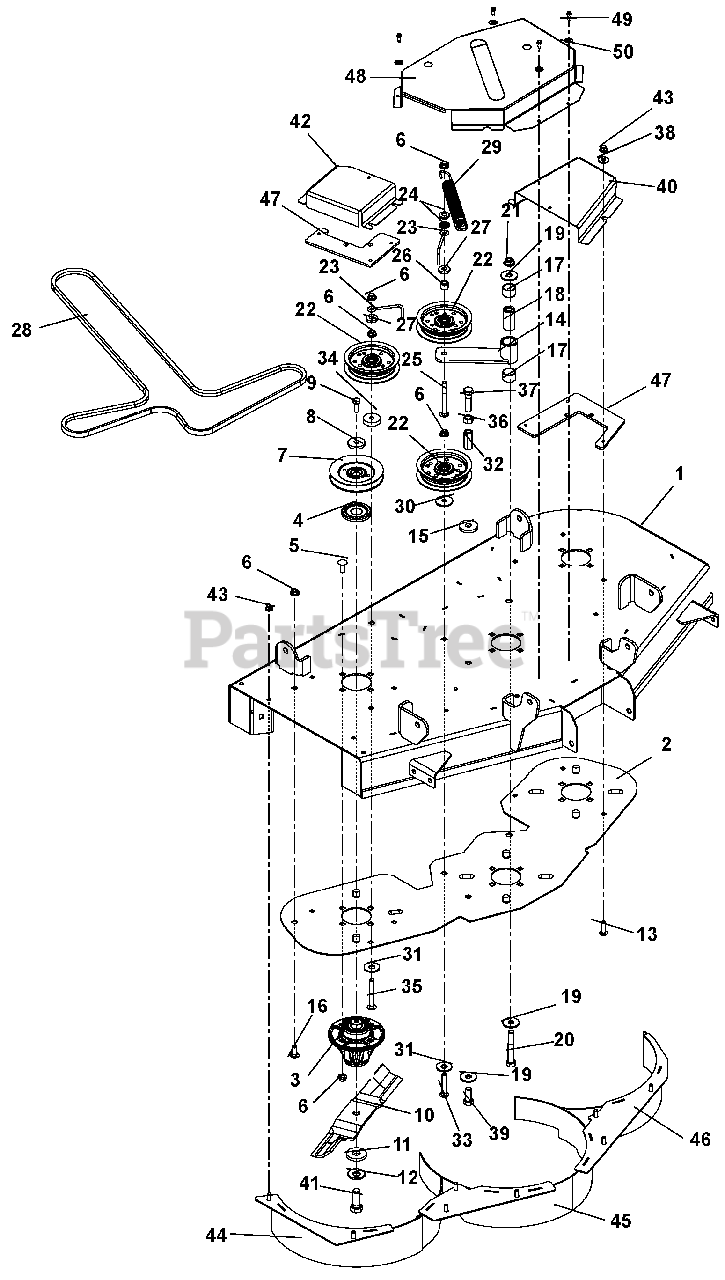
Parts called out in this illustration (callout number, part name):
1	XL – Deck Kit CE
2	Doubler Plate, 42" Deck
3	Spindle Assembly
4	Dust Cap
5	Bolt, Round Head Square Neck .38-16 x 1.25 Grade 5
5	Bolt, Round Head Square Neck .38-16 x 1.50 Grade 5
6	Nut, .38-16 Nyloc Flange
7	Pulley, Spindle
8	Washer, Flat Steel .406 x 1.50 x .245
9	Bolt, Hex .38-16 x 1.00 EP30
10	Blade, Mulch 14.50"
11	Washer, Flat .640 x 1.75 x .250
12	Washer, Bellville .63 x 1.625 x .14
13	Bolt, Serrated Hex Flange Washer Head .312-18 x .50
14	Idler Arm
15	Washer, Flat Steel .515 x 1.625 x .250 YZ
16	Bolt, Round Head Square Neck .38-16 x 1.00 Grade 5
17	Bearing, 1.00 x 1.12 x .75
18	Bushing, Spacer .505/.500 x .999/.996 x 2.05/2.03 Promaster
19	Washer, Flat Steel .511 x 1.441 x .125
20	Bolt, Hex .50-13 x 3.50 Grade 5
21	Nut .50-13 Nyloc Flange
22	Assembly, Idler 4"
23	Belt Finger
24	Bushing, Flange .406 x .88 x .270 x .140
25	Bolt, Round Head Square Neck .38-16 x 3.50 Grade 5
26	Bushing, Sleeve .391 x .688 x .52
27	Washer, Flat Steel .406 x 1.00 x .188
28	Belt, HA 127.12 Wrapped
29	Extension Spring
30	Washer, Flat Steel .39 x 1.5 x .125
31	Plate, Idler Mount Reinforcement
32	Nut, Coupling .50-13 x 1.75
33	Bolt, Round Head Square Neck .38-16 x 2.25 Grade 5
34	Spacer, .39 x 1.50 x .380
35	Bolt, Round Head Square Neck .38-16 x 3.50 Grade 5
36	Nut, Hex .50-13
37	Bolt, Hex .50-13 x 2.00 Grade 5
38	Washer, Flat Steel .38 x .875 x .083
39	Bolt, Hex .50-13 x 1.25 Grade 5
40	Belt Cover, Left
41	Bolt, Hex .62-18 x 1.75 Grade 8
42	Belt Cover, Right
43	Nut, .31-18 Nyloc Flange
44	Weldment, 42 Baffle Right Hand
45	Weldment, 42 Mulch Baffle (CTR)
46	Weldment, 42 Mulch Baffle Left Hand
47	Bracket, Belt Cover Mount - LHS
47	Bracket, Belt Cover Mount - RHS
48	CE Belt Guard
49	Screw, tap .25-20x.50
50	Nut, push .25x.50
